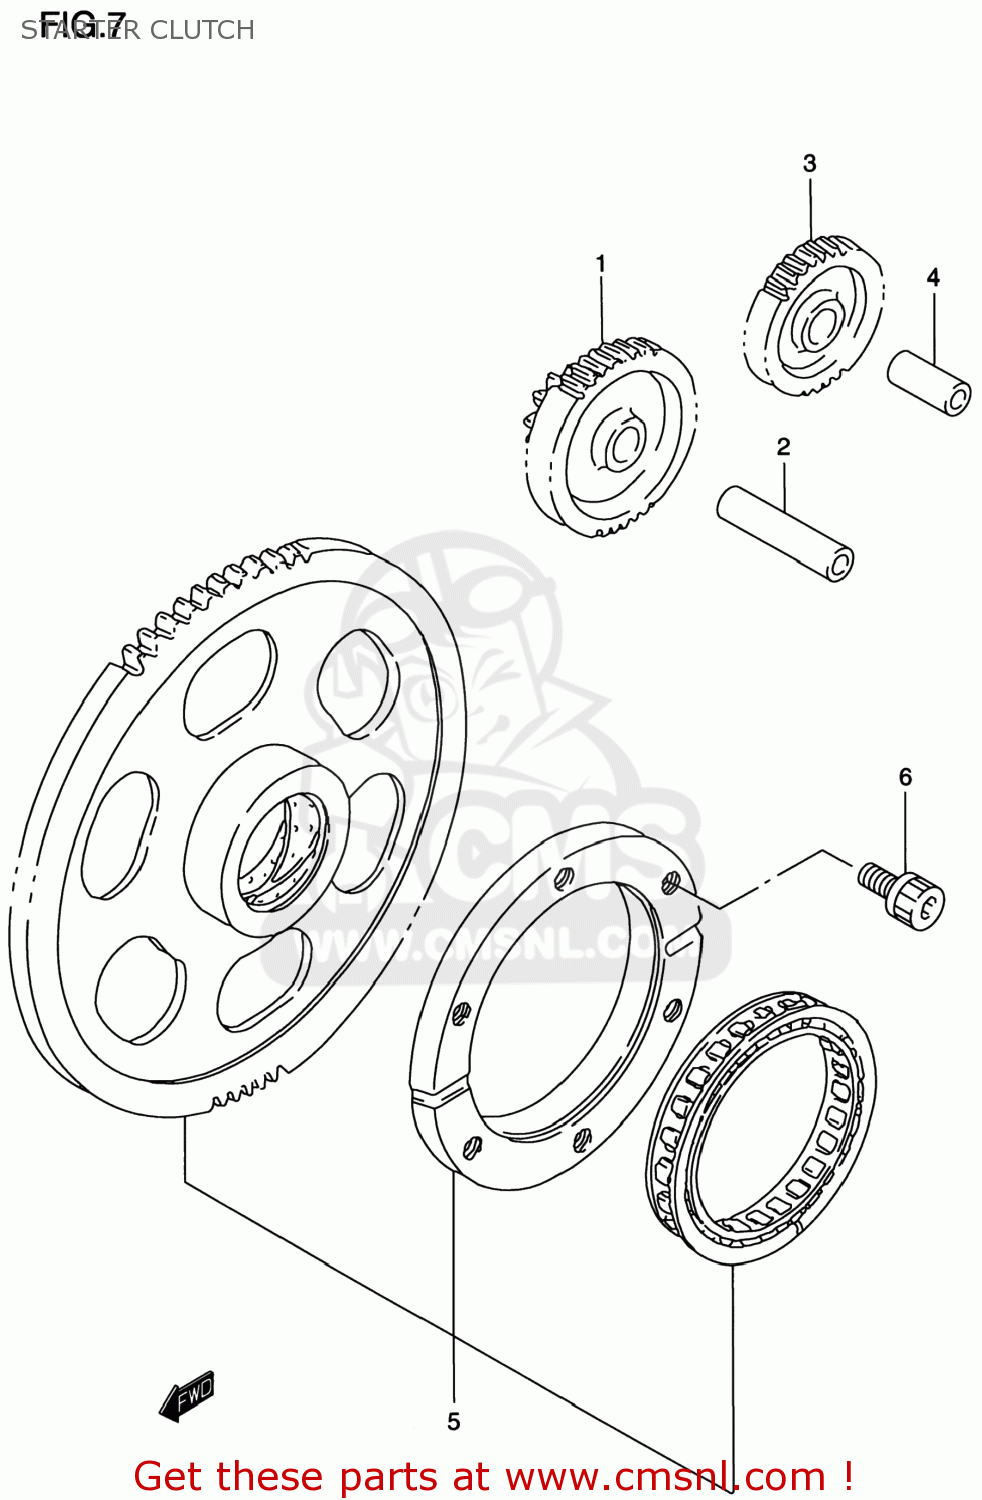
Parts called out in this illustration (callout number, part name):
1	GEAR,STARTER IDLE NO.1
2	PIN,10X43
3	GEAR,STARTER IDLE NO.2
4	PIN
5	CLUTCH SET,STARTER
6	BOLT
